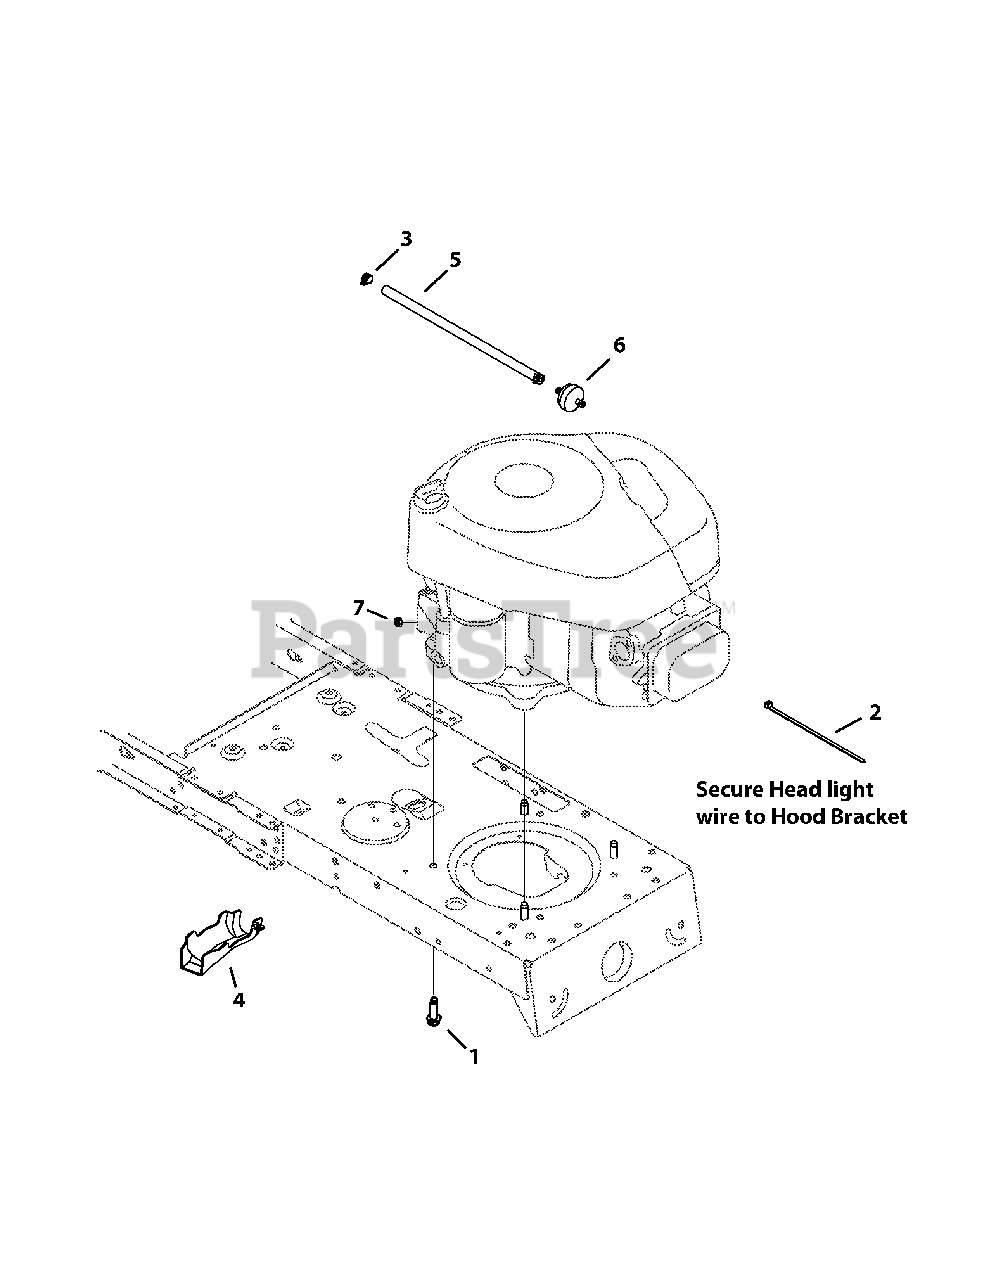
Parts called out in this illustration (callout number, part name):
1	Screw, 3/8-16 x 1.0
2	Cable Tie
3	Clamp Hose, .490 diameter
4	Oil Drain Sleeve
5	Fuel Hose, Low Permeation
6	Fuel Filter
7	Nut, M6, Hexlock
